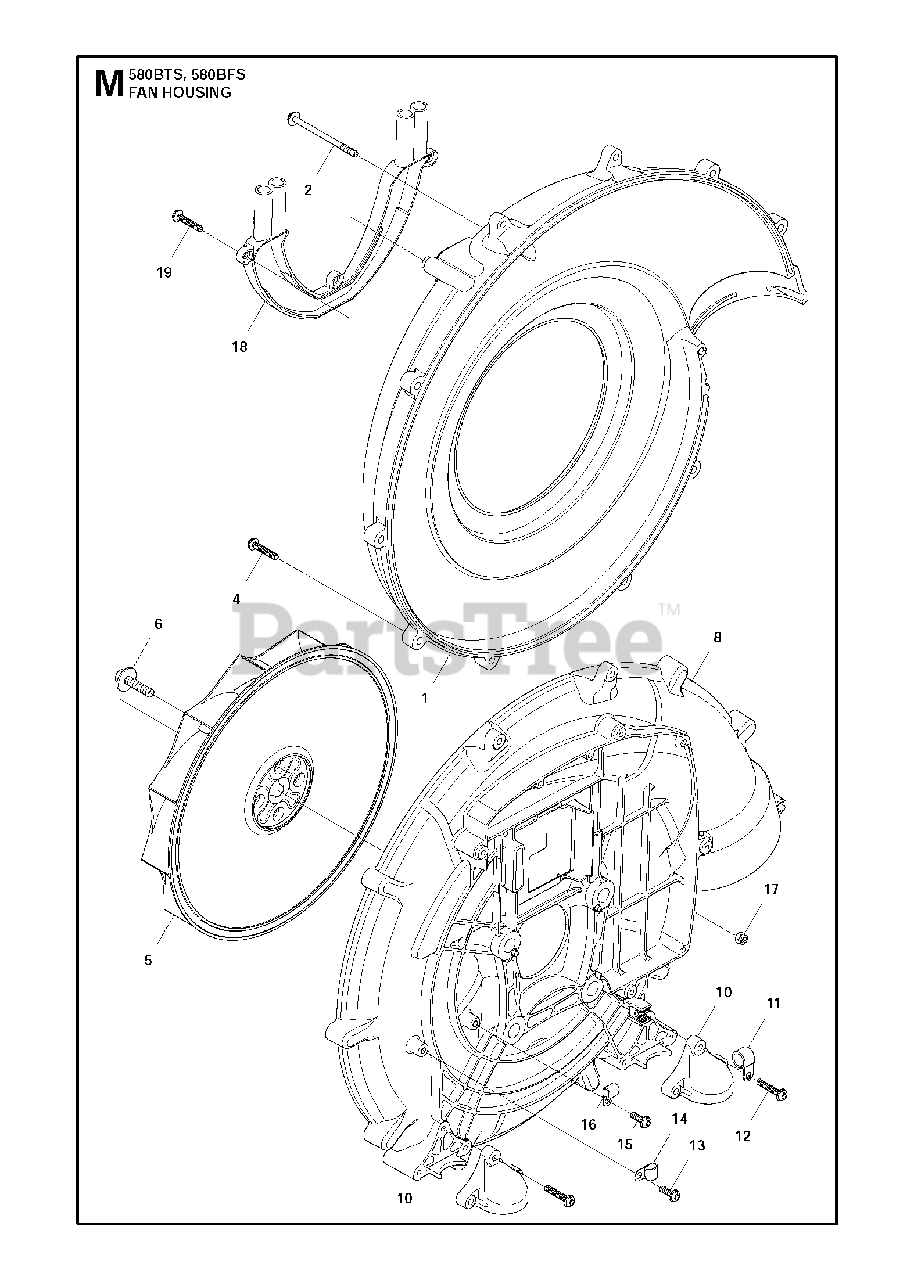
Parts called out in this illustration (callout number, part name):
1	COVER VOLUTE
5	FAN
8	CASE VOLUTE
10	BRACKET DAMPNER
11	CLAMP
14	CLAMP
16	CLAMP
